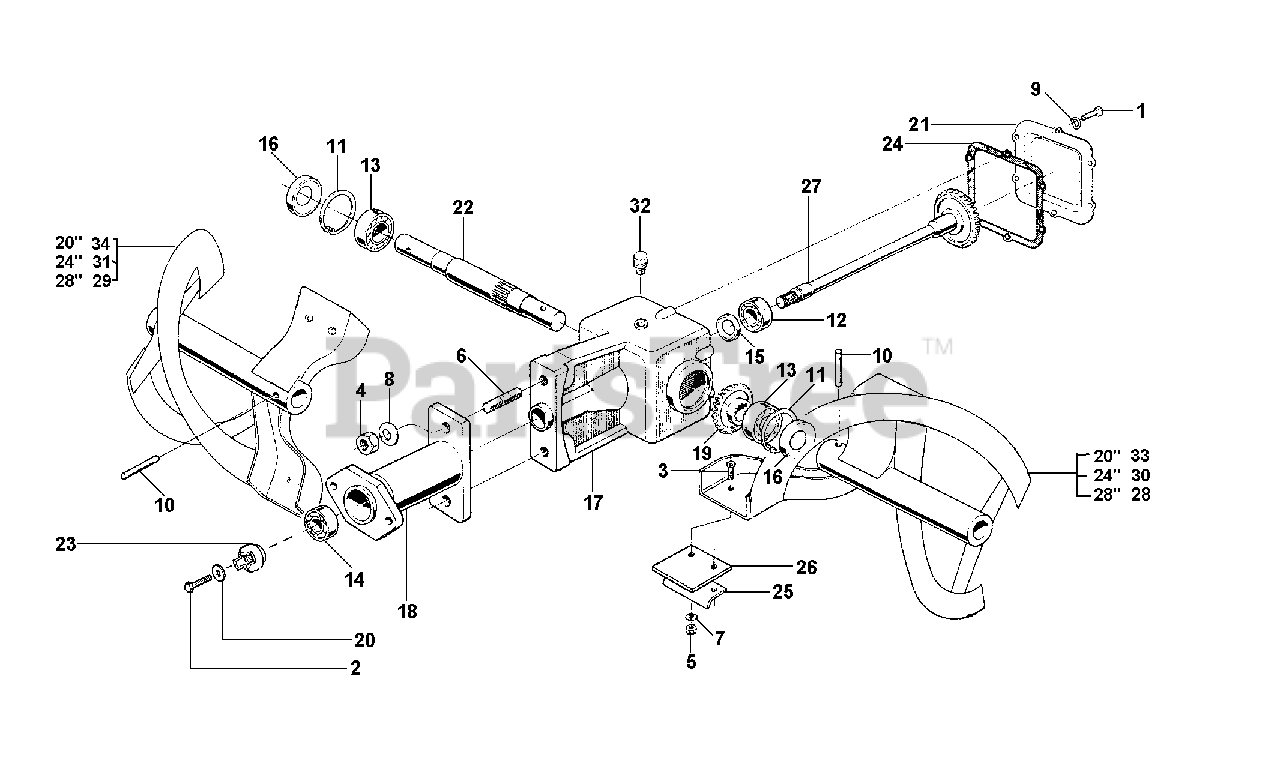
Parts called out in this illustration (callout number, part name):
1	SCREW M6X12
2	SCREW TE M6X16
3	SCREW TSVEI M6X20
4	NUT M16 UNI 5588-5S
5	NUT, SELF LOCKING M6
7	WASHER, FLAT 6.4
8	SUPER WASHER
9	WASHER, LOCK 6.4
10	PIN, LOCKING 10X50 DIN 1481
11	CIRCLIP, INTERNAL D 62
12	BEARING SKF 25X52X15 6205
13	BEARING 30X62X16 6206
14	BEARING 20X47X14 6204 2RS
15	OIL SEAL 25X40X7
16	OIL SEAL STANDARD 30X62X10
17	SNOW THROWER CASING
20	WASHER 7X25X4
21	SNOW THROWER CASING COVER
22	TURBINE SHAFT
23	PTO COUPLER
24	SNOW THROWER CASIG GASKET
26	RUBBER FLAP
27	DRIVE SHAFT
28	RIGHT TURBINE 70 CM
29	LEFT TURBINE 70 CM
30	RIGHT TURBINE 60 CM
31	LEFT TURBINE 60 CM
32	BREATHER CAP 1/4 GAS
33	RIGHT TURBINE 50 CM
34	LEFT TURBINE 50 CM
